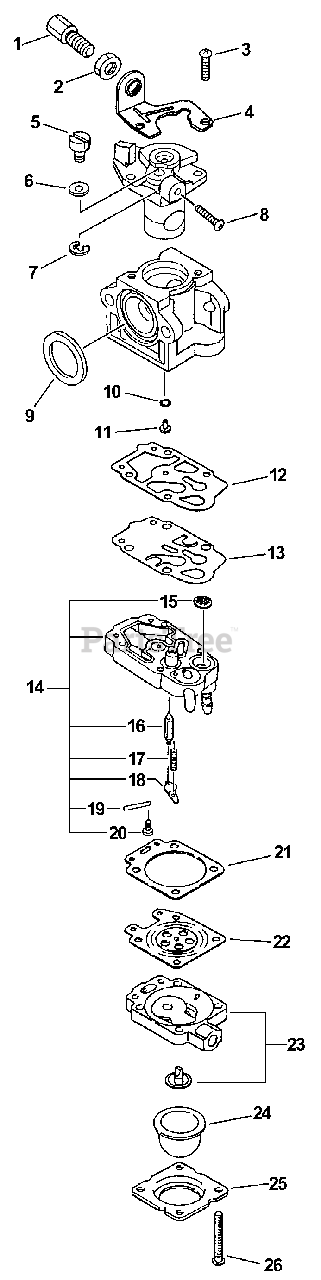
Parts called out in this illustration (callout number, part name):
1	NUT, CABLE ADJUST
4	BRACKET, THROTTLE CABLE
7	RING, RETAINING
8	SCREW, IDLE ADJUST
9	SEAL
10	NEEDLE - MIXTURE
11	JET, MAIN
12	GASKET, PURGE
13	DIAPHRAGM, PURGE
14	BASE, PURGE
15	STRAINER
16	VALVE, INLET NEEDLE
17	SPRING, METERING LEVER
18	LEVER, METERING
19	PIN, METERING LEVER
20	SCREW, METERING LEVER PIN
21	GASKET, METERING
22	DIAPHRAGM, METERING
23	PURGE BASE ASSY
24	BULB, PURGE
25	RETAINER, PURGE BULB
26	SCREW, PUMP COVER
